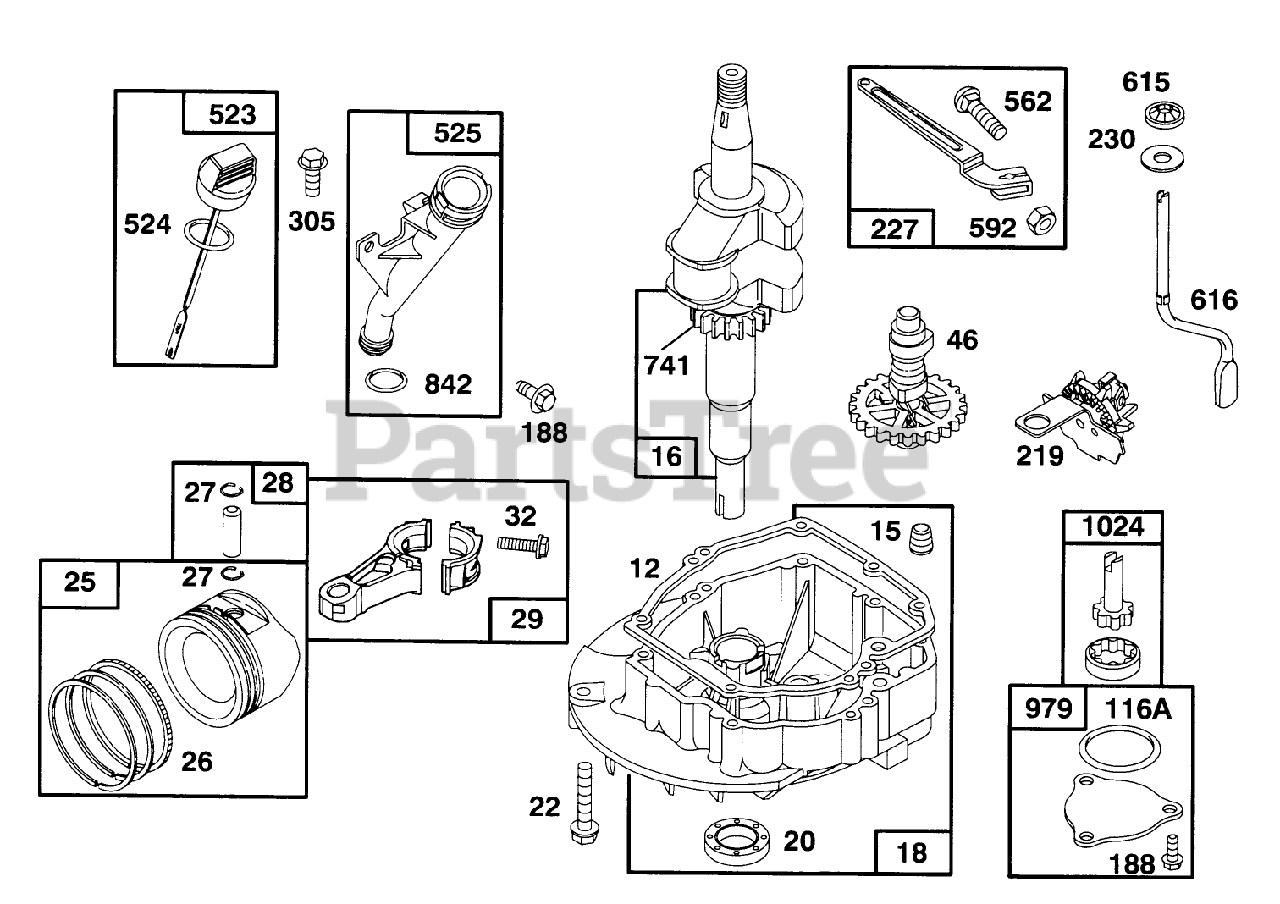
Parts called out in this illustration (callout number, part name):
12	ENGINE BASE GASKET
15	PIPE PLUG
20	SEAL-OIL
25	STD PISTON ASSEMBLY
27	PISTON PIN LOCK
28	PIN ASM - PISTON
29	CONNECTING ROD
116A	O RING SEAL
219	GOVERNOR/OIL SLINGER
227	GOVERNOR LEVER ASSEMBLY
305	SCREW - HEX HEAD
524	O-RING
562	GOVERNOR LEVER BOLT
592	HEX NUT
842	O-RING
979	OIL PUMP COVER
1024	OIL PUMP
